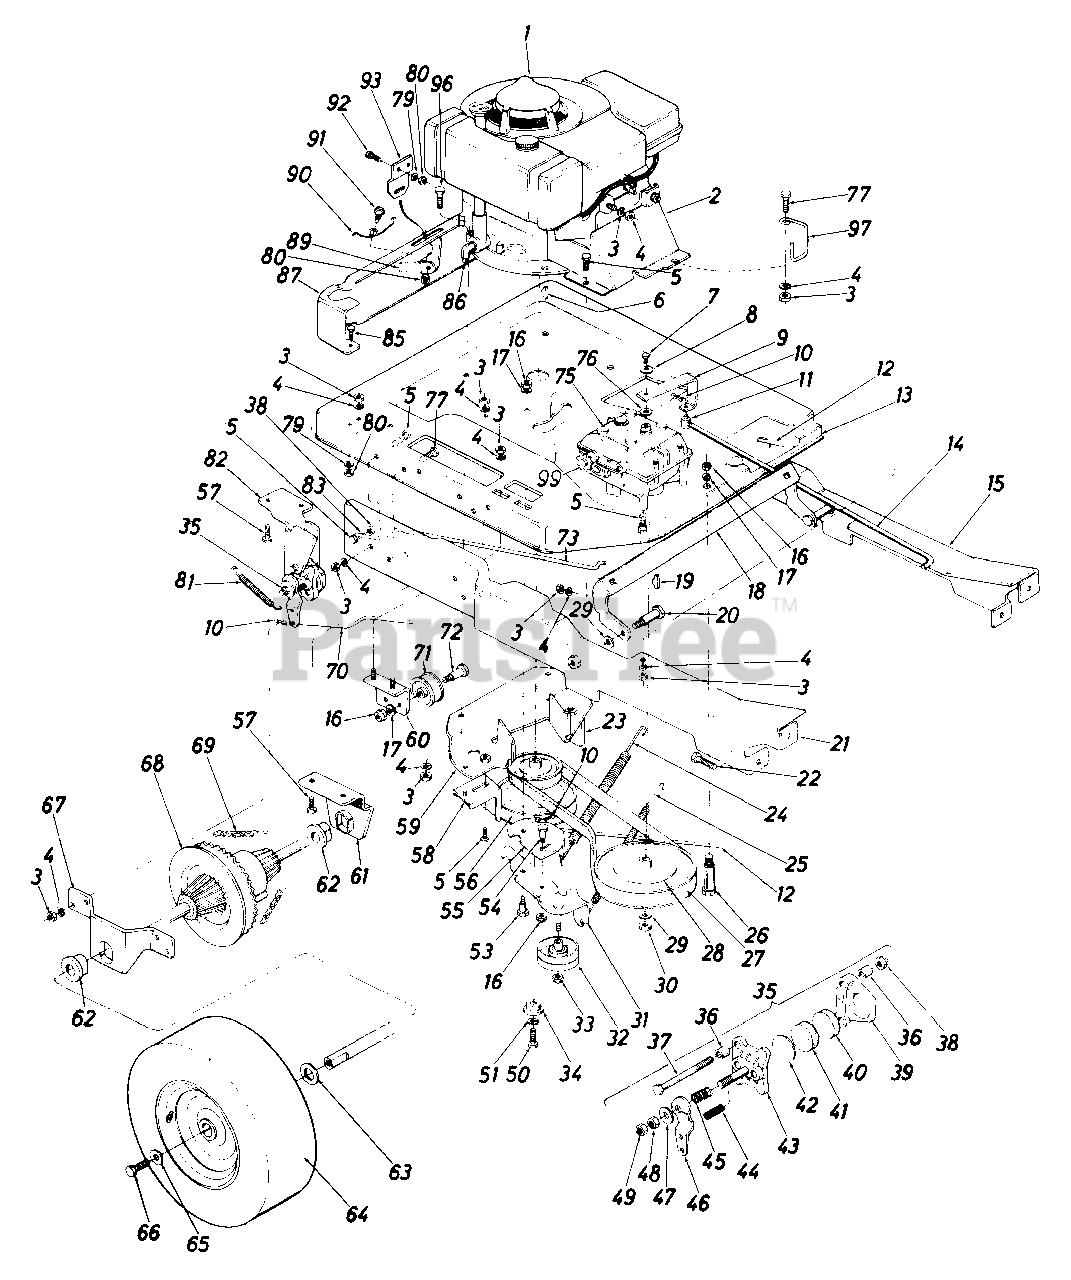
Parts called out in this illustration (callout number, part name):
1	Engine
2	Hot Air Duct
3	Hex Nut 5/16-18 Thd.
4	L-Wash. 5/16 Scr.
5	Hex Sems Scr. 5/16-18 x .75
6	#6 Hi-Pro Key 5/32 x 5/8 Dia.
7	Hex Scr. 5/16-24 x .50 Lg.
8	Belleville Wash. .345 I.D.
9	Shift Brkt.
10	Cotterpin 3/32 x .75
11	Adjustment Ferrule
12	Clutch Rod
13	Engine Mtg. Plate
14	Shift Rod
15	Side Rail L.H.
16	Hex Cent. L-Nut 3/8-16 Thd.
17	Spring L-Wash. 3/8 Scr.
19	#4 Hi-Pro Key 3/32 x 5/8" Dia.
20	Shld. Scr. .625 Dia. x 1.5" Lg.
21	Side Rail Ass'y. R.H.
22	Hex Scr. 3/8-16 x .75 Lg.
23	Belt Keeper
24	Ext. Spring
25	Tension Spring
26	Shld. Scr. .62 x 1.75
27	V-Belt 1/2 x 48
28	Transmission Pulley
29	Spring L-Wash. 1/2 Scr.
30	Hex Jam Nut 1/2-20
31	Idler Brkt. Ass'y.
32	Flat Idler
33	Hex Ins. L-Nut 3/8-24
34	Step Washer
35	Brake Ass'y. - Comp.
37	Hex Scr. 5/16-18 x 2.25 Lg.
38	Hex Cent. L-Nut 5/16-18 Thd.
39	Casting Carrier
40	Friction Pad 1.110 Dia. x .245 Thick
41	Friction Pad 1.110 Dia. x .430 Thick
42	Back Up Washer
43	Casting Cam
47	Washer
48	Hex Top L-Nut
49	Hex Centerlock Nut
50	Hex Scr 3/8-24 x 1.75 Lg. H.T.
51	Spring-Wash. 3/8 Scr.
53	Shld. Scr. .500 Dia. x .340
54	Shld. Scr .500 Dia. x .170
55	Idle Pilot Brkt.
56	Two Step Engine Pulley
58	Belt Keeper
59	Belt Guard Ass'y.
60	Chain idler Assy.
61	Bearing Support
62	Flange Bearing - Plastic
63	Flat Washer .812 I.D.
64	Rear Wheel Ass'y. - Comp.
65	Belleville Washer
66	Hex Scr. w/Lock 5/16-24 x .75 Lg.
67	Bearing Brkt.
68	Differential Assy. - Comp.
69	#420 Chain 1/2 x 71 Links
70	Brake Rod
71	Flat Idler
72	Shld. Scr. .500 x .48 Lg.
73	Rear Cover Prop
75	Transmission 4 Speed - Peerless
76	Hardened Washer
77	Hex Sems Scr. 5/16-18 x 1 Lg.
79	L-Wash. 1/4 Scr.
80	Hex Nut 1/4-20 Thd.
81	Brake Return Spring
82	Brake Hanger Brkt.
83	Flat Wash. .304 I.D.
85	Hex Scr. 1/4-20 x .50 Thd.
86	90° Elbow Male to Female 3/8" Thd.
87	Rear Panel
89	Hook Brkt.
91	Shld. Scr.
92	Carr. Bolt 1/4-20 Thd.
93	Latch Brkt.
96	Hex Scr. 5/16-18 x 1-1/2 Lg.
97	Belt Guide
